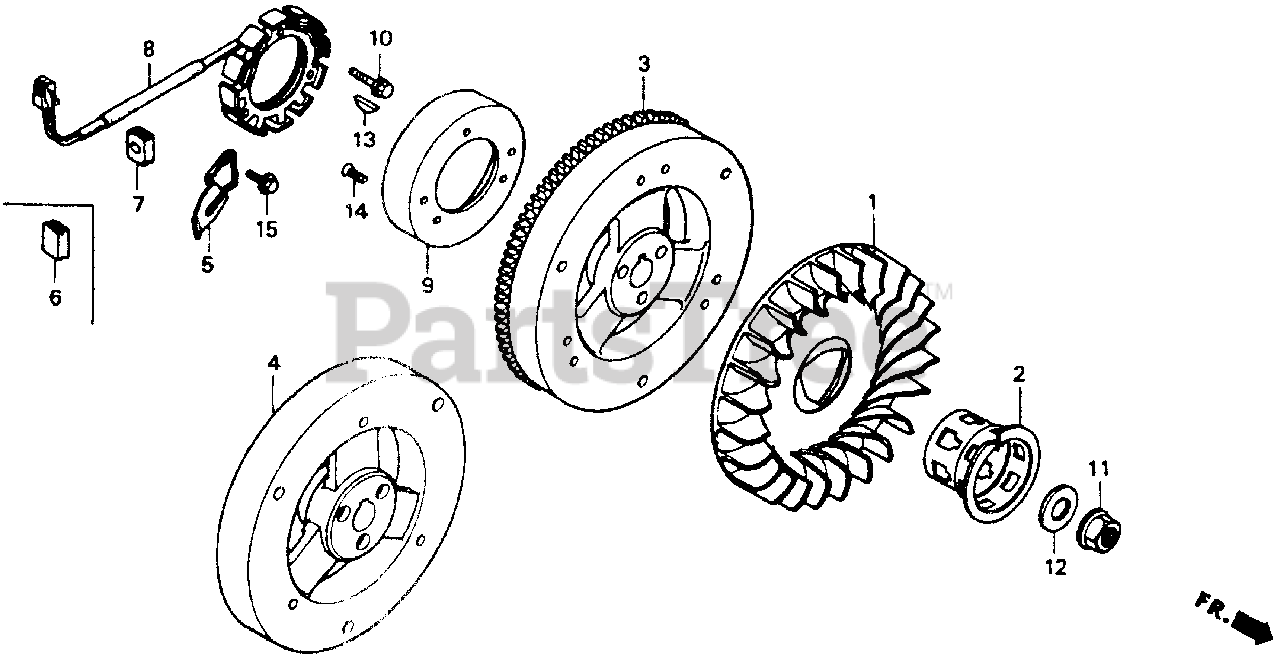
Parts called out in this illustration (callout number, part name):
1	FAN, COOLING
2	PULLEY, STARTER
4	FLYWHEEL (N3)
6	GROMMET, WIRE
11	NUT, FLANGE (20MM)
12	WASHER (20MM)
13	KEY, WOODRUFF (50X7)
